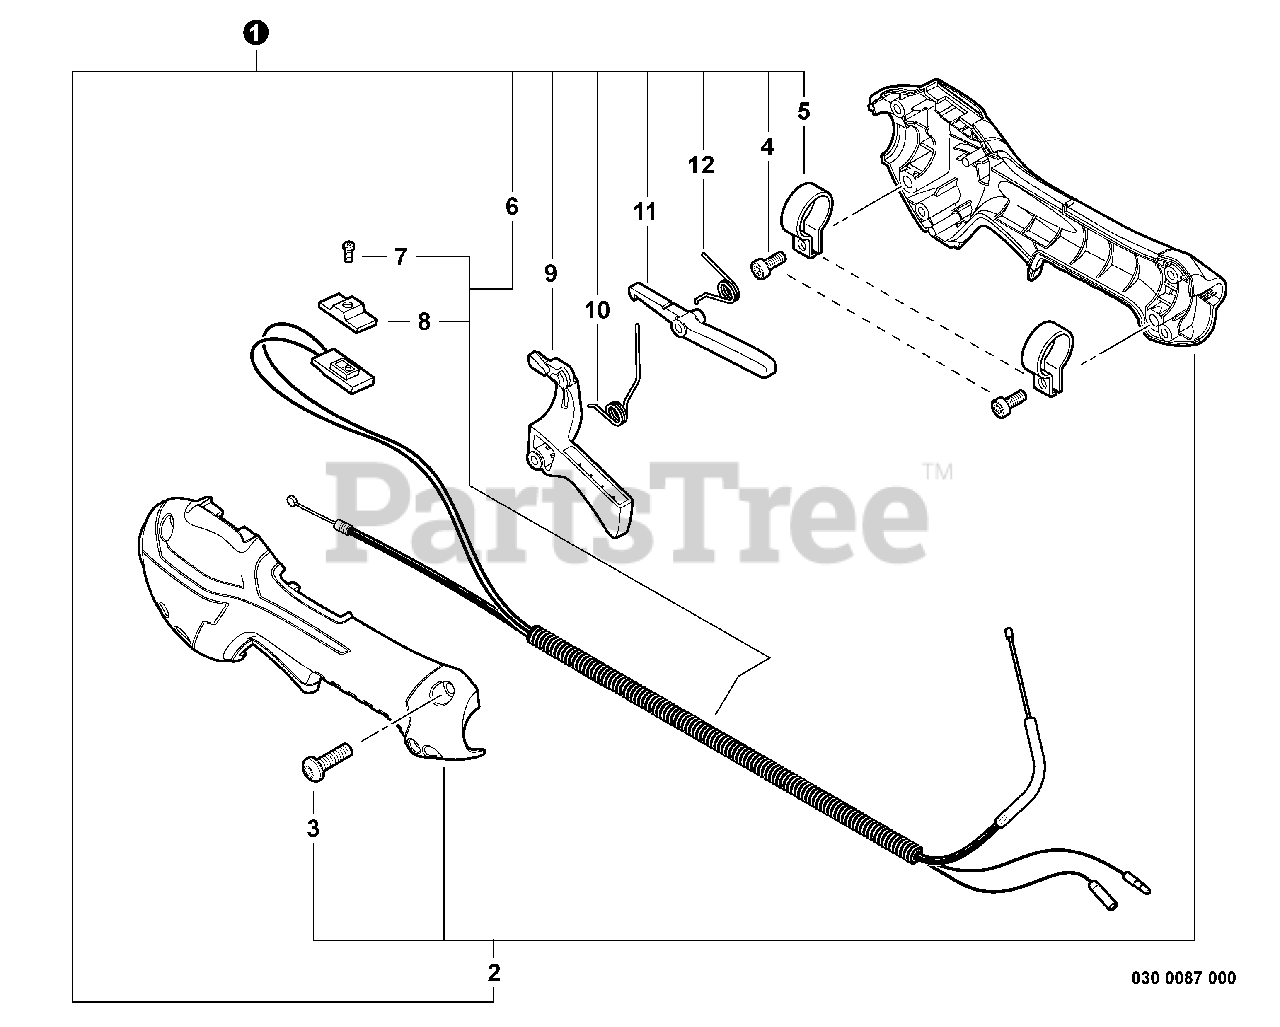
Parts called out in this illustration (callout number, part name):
1	CONTROL HANDLE ASSY
2	CONTROL HANDLE KIT
3	SCREW - 5X16
4	SCREW - 5X16
6	CONTROL CABLE ASSY
7	SCREW - 3X10
8	KNOB, SWITCH - ORANGE
9	TRIGGER, THROTTLE
10	SPRING, TRIGGER
11	LEVER, TRIGGER LOCKOUT
12	SPRING, LOCKOUT LEVER
